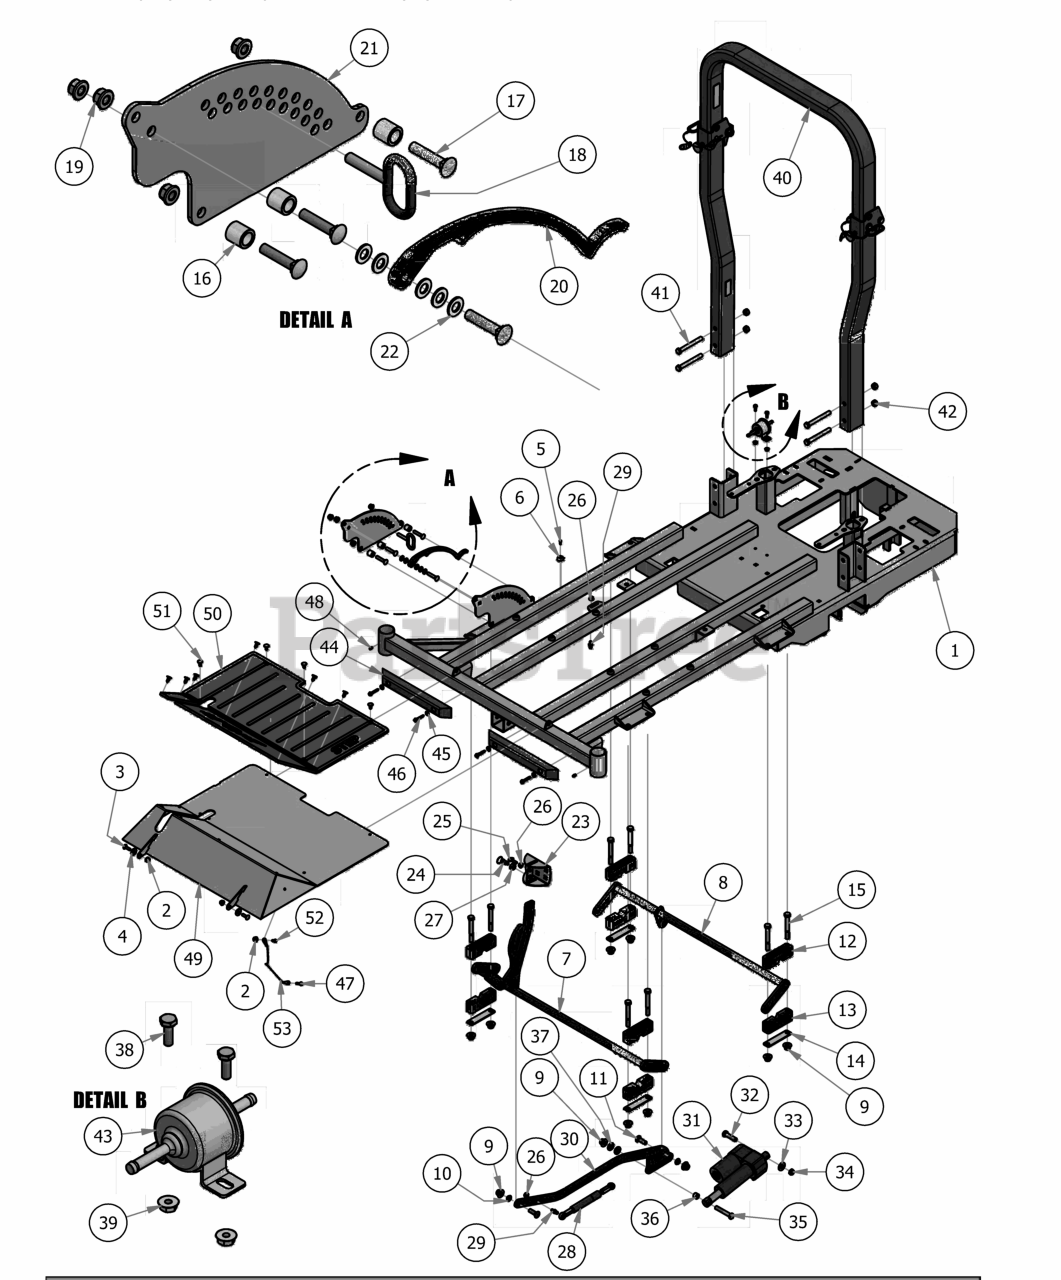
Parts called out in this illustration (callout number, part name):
1	Outlaw Diesel Frame
2	5/16-18 Nylon Flange Nut
3	5/16" x 1" Carriage Bolt
4	.360 ID Plastic Washer
5	#10 x 1/2" Self Tapping Screw
6	Button Bumper
7	2015 Outlaw Act Bar Assembly (Front)
8	2015 Outlaw Act Bar Assembly (Rear)
9	1/2-13 Nylon Flange Nut
10	Bushing- SF-1620-4
11	1/2 x 1-1/2 Carriage Bolt
12	Two Piece Pillow Block (Male)
13	Two Piece Pillow Block (Female)
14	Two Piece Pillow Block Strap
15	1/2" x 4" Bolt (Grade 8)
16	Spacer 3/4 OD x 1/2 ID x 3\4 Length
17	3/8 x 1 3/4 Carriage Bolt
18	Deck height lever pin
19	3/8" Nylock Flange Nut
20	Outlaw Deck Lever Lock
21	Outlaw Height Indicator Plate (Outer)
22	.390 x .750 x .062 Nylon Washer
23	Outlaw Deck Lift Pedal
25	5/16-18 x1 Thumb Screw Zinc
26	5/16" Flange Nut
27	1/2" Hex Nut
28	250lb Gas Spring
29	10mm Damper Ball Stud-Steering
30	Outlaw Linkage Bar Susp Frame
32	1/2-13x2 Grade 8 Hex Bolt
33	1/2" Washer (Grade 8)
34	1/2" Nylock Nut (1/2 Jam)
35	1/2" x 3" Hex Bolt
36	1/2 x 1/2 Spacer
37	.505 Nylon Spacer
38	1/4" x 3/4" Hex Bolt
39	1/4-20 Hex Flange Nuts Zinc w/Serrations
40	2014 & Newer Diesel 2x3 Folding ROPS
41	1/2" x 4 1/2" Bolt
42	1/2" Center Lock Nut
43	Electric Fuel Pump
44	14" Rubber Bumper
45	1/4" Flat Washer
46	1/4" x 1 1/2" Self Tapping Screw
47	1/4 x 1 Hex Head tek screw
48	1/4" Press in Grease Fitting
49	Compact Diesel Floorboard
50	Foot Assist Floor Mat
51	Ratchet Fastener
52	1/4" x 5/8" BS C/S 18-8 SS
53	Floor board Cable W/ Swivel Ends
